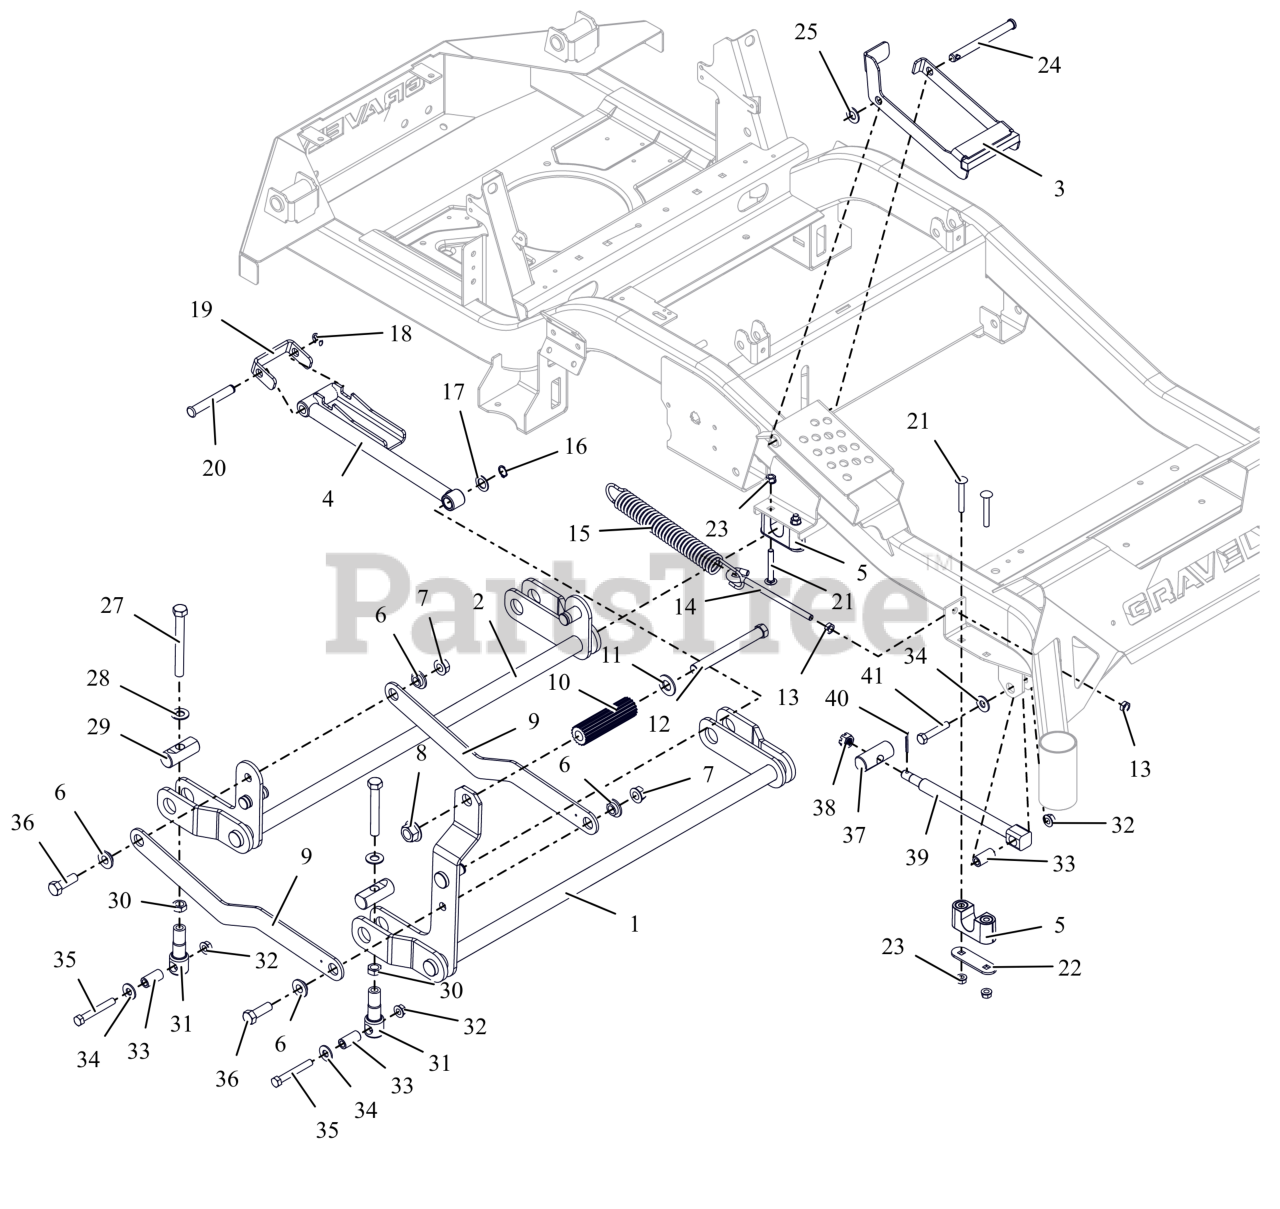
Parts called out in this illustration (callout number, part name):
1	WLDMT, FRONT DECK LIFT PIVOT
2	WLDMT, REAR DECK LIFT PIVOT
3	WLDMT, HOC TRANSFER LOCK (BLACK)
4	WLDMT, HOC LIFT ARM (BLACK)
5	ASM-BUSHING, DECK LIFT
6	BSHG-FLG .515X.750X.310X1.120
7	NUT-LK-TOP-FLG .500-13 GF ZCC
8	NUT,FLG-TOP LK .625-11 FBP
9	LINK, DECK
10	ROD, FOOT PEDAL (BLACK)
11	WSHRFLT 5/8SAE CARBHARD FBP
12	BLT, HEX .62-11X5.50 G5 FBP
13	NUT-JAM .375-16 GR2 E-COAT
14	BOLT- J-HOOK.38-16X5.25 E-COAT
15	SG-TENS.162X1.25X8.25 E-COAT
16	RG-RTNG-EXT .625X.050
17	WSHR, FLT .630X1.005X.062 ZCC
18	RG-RTNG-EXT .500X.042 (E)
19	BRKT, HOC LINE
20	PIN, .499/.494 x 3.385 CLEVIS
21	BLT, RHSSN.31-18X2.25 G5 ZCC
22	PLATE, BEARING SUPPORT
23	NUT,LK-CTR-FLG .31-18 GF ZCC
24	PIN, SLIC-.500X4.97X4.55 -ZC
25	WSHR-FL-NYL .518X1.000X.080
26	BLT, HEX 0.5-13X3.5F GR5 ZCC
27	BLT, HEX .50-13X4.50F G8 ZCC
28	WSHR, FLT .557X1.040X.102 ZCC
29	PIN, DECK LIFT
30	NUT-JAM .500-13 G2 ZCC
31	LINK, DECK LIFT FORMED
32	NUT-LK-TOP-FLG .38-16 ZC120
33	SPACER, DECK LEVELING
34	WSHR,FLT .438X1.00X.083 ZCC
35	BLT, HEX .38-16X2.75 G8 ZCC
36	BLT,HEX .50-13X1.50 G5 ZCC
37	PIN, DECK LIFT
38	NUT-SL .50-13
39	DRAG,LINK-HD
40	PIN,CTR.12X1.25EXTPRSQCT ZC120
41	BLT,HEX .38-16X2.00 G5 ZCC
